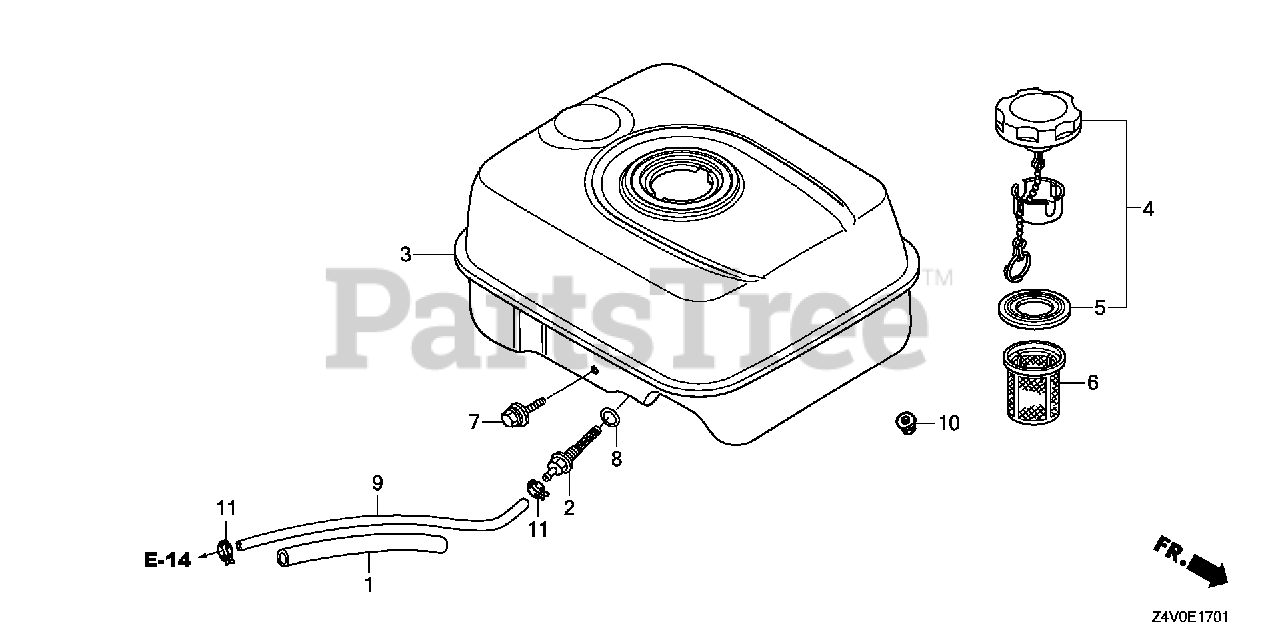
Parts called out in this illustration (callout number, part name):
1	RUBBER, SUPPORTER (107MM)
2	JOINT, FUEL TANK
3	TANK, FUEL *NH31* (MCKINLEY WHITE)
4	CAP, FUEL FILLER
5	GASKET, FUEL FILLER CAP (39X62X3) (RADICON)
7	BOLT, FLANGE (6X34)
8	O-RING (13.5X1.5) (ARAI)
8	O-RING (14MM) (NOK)
9	TUBE, FUEL (4.5X145) (FKM)
10	NUT, FLANGE (6MM)
11	CLAMP, TUBE (D8)
